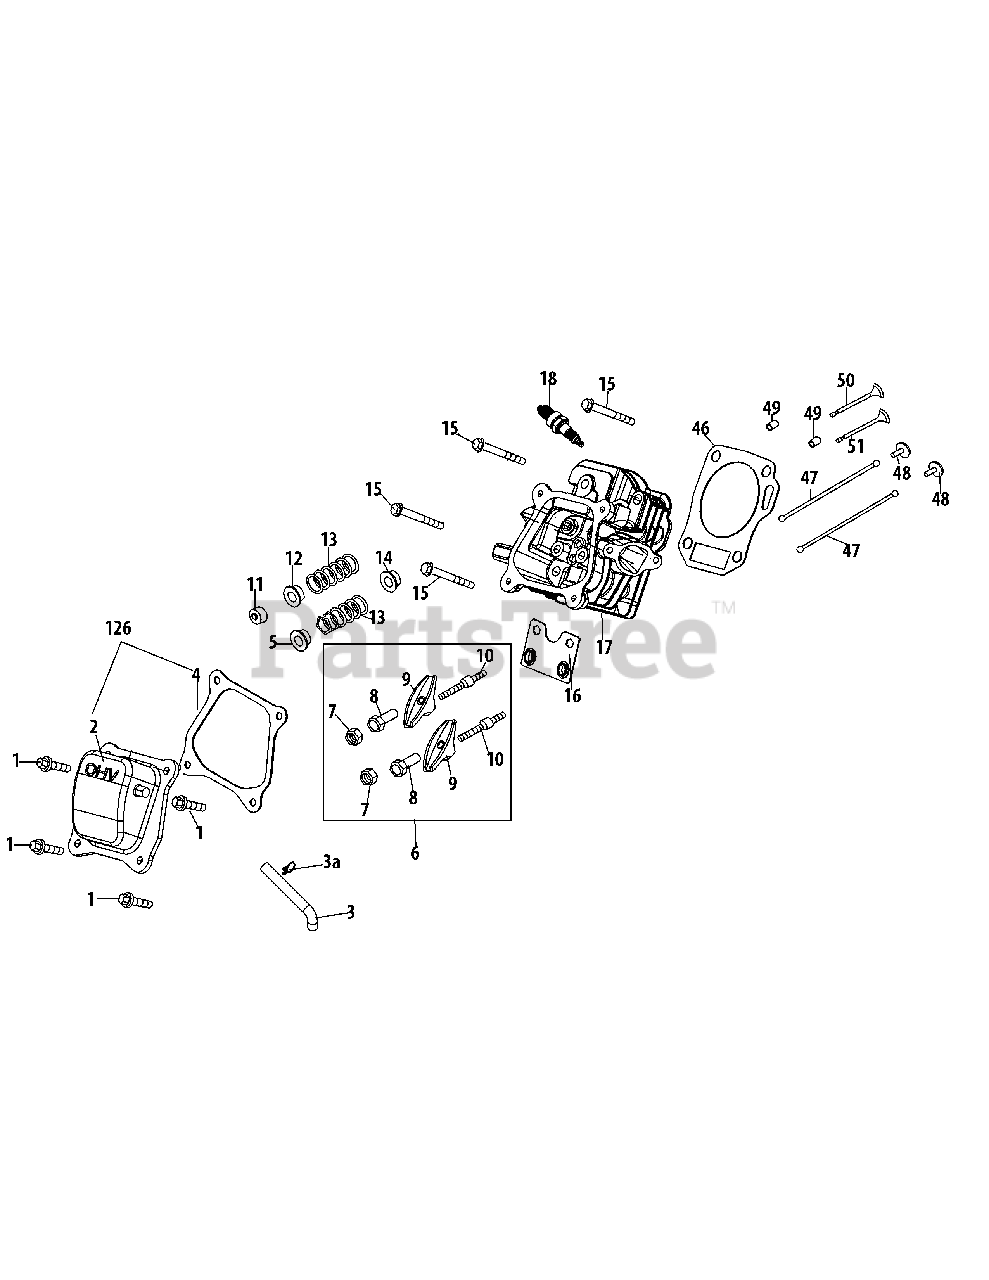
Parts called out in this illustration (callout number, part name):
1	Bolt M6×16
2	Valve Cover
3	Breather Hose
4	Valve Cover Gasket
5	Retainer, In.Valve Spring
6	Rocker Arm Assembly
7	Nut, Pivot Locking
8	Adjusting Nut ,Valve
9	Rocker Arm
10	Bolt, Pivot
11	Adjuster, Exh Valve
12	Retainer, Ex.Valve Spring
13	Valve Spring
14	Intake Valve Seal
15	Bolt M8×55
16	Push Rod Guide
17	Cylinder Head Assembly
18	Spark Plug/F6Rtc
46	Gasket, Cylinder Head
47	Push Rod Kit
48	Tappet
49	Dowel Pin 10×16
50	Valve Kit
51	Valve Kit
126	Valve Cover Kit
